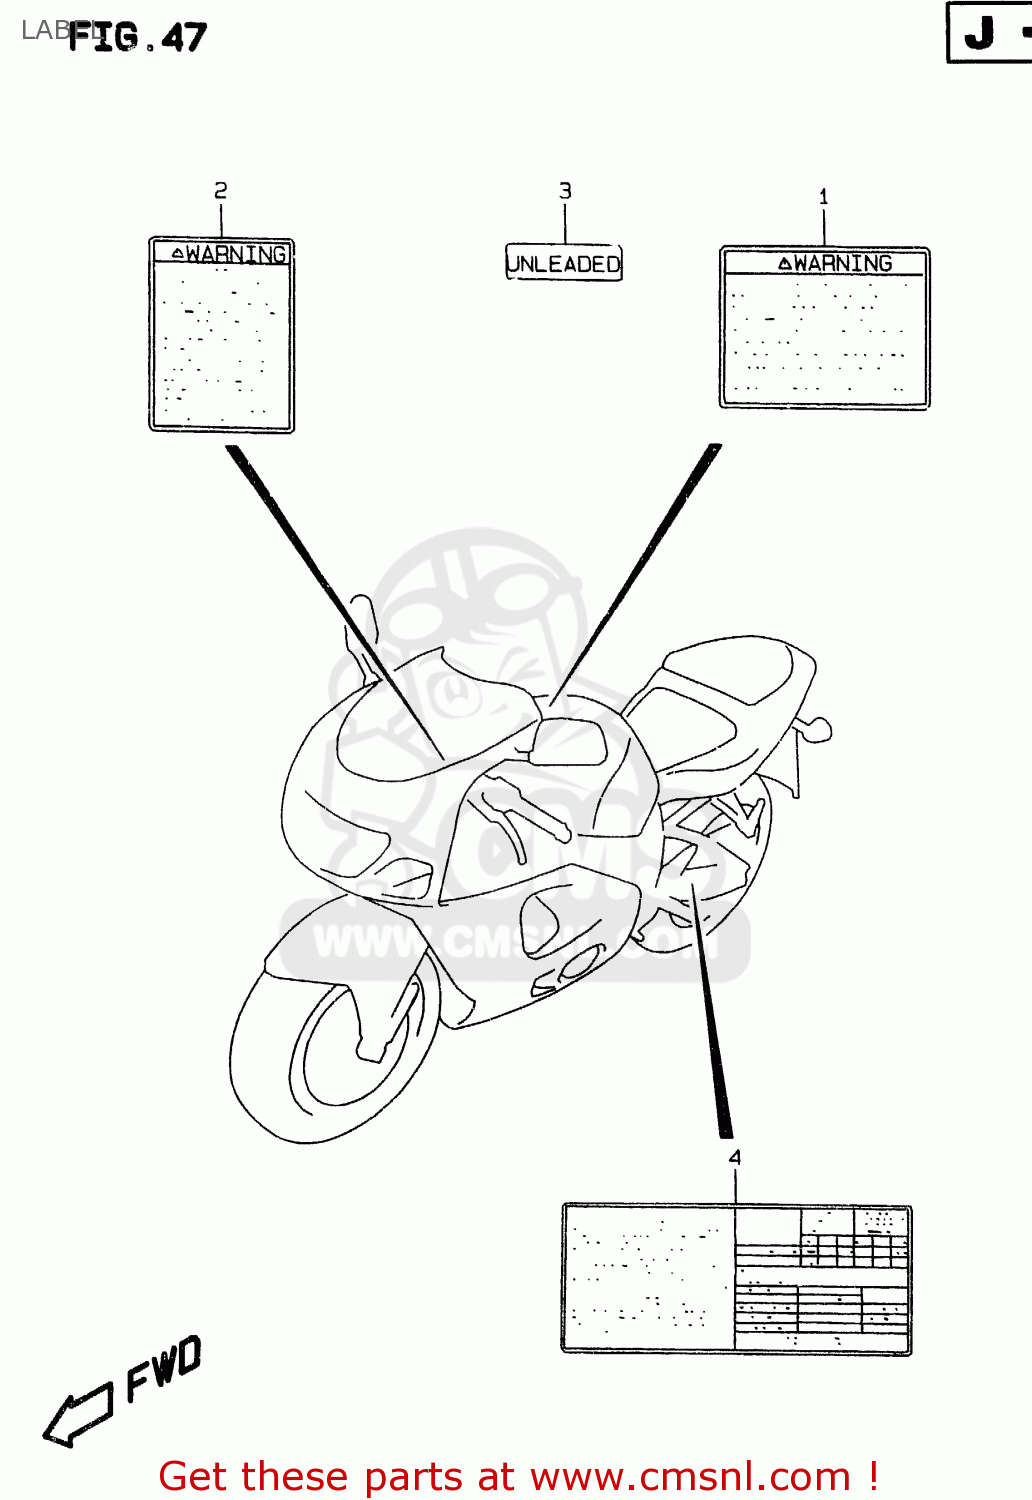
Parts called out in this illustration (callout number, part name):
1	LABEL,WARNING
2	LABEL (WARNING SCREEN)
3	LABEL,CAUTION
4	LABEL,TIRE INFORMATION
5	MANUAL, OWNER'S
